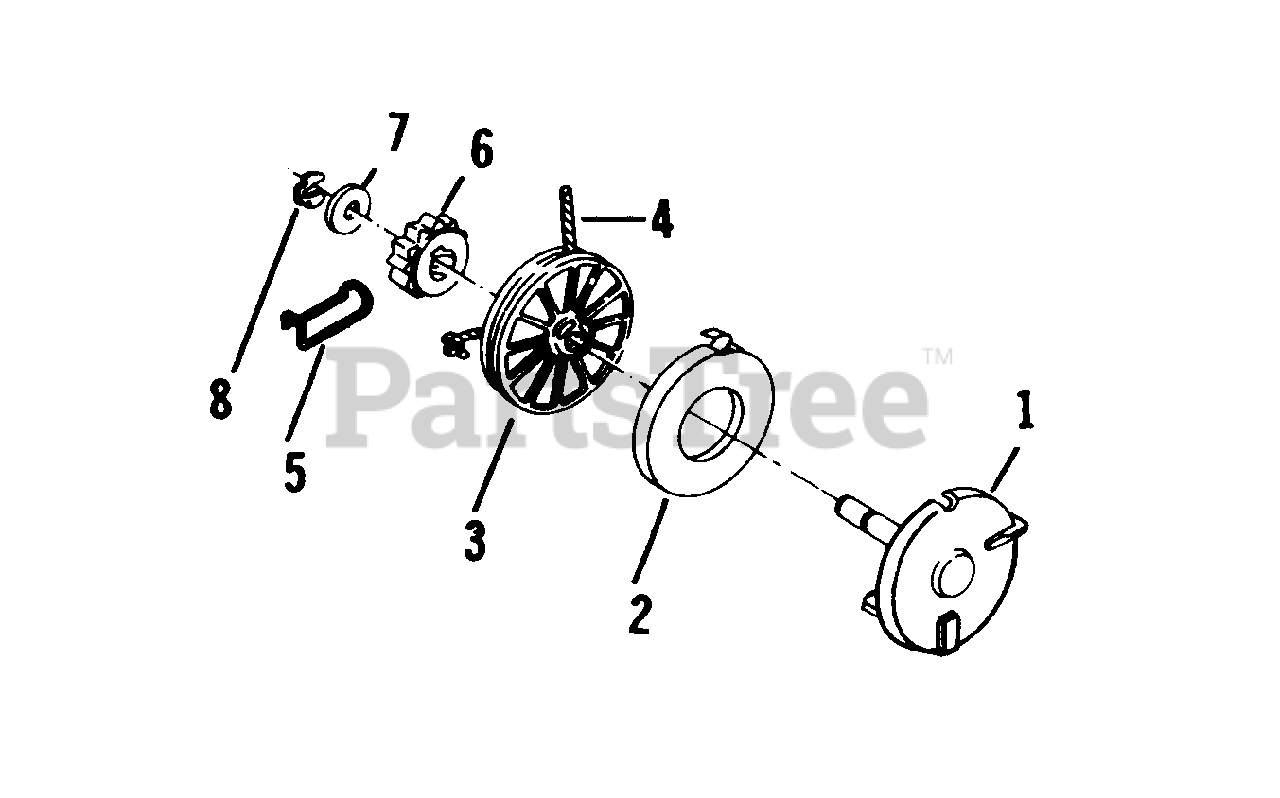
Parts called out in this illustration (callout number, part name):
1	Spring Cup and Pin Assembly
2	Spring and Retainer Assembly
3	Pulley
4	Rope
5	Spring-Drag
6	Pinion
7	Washer
8	Retainer
